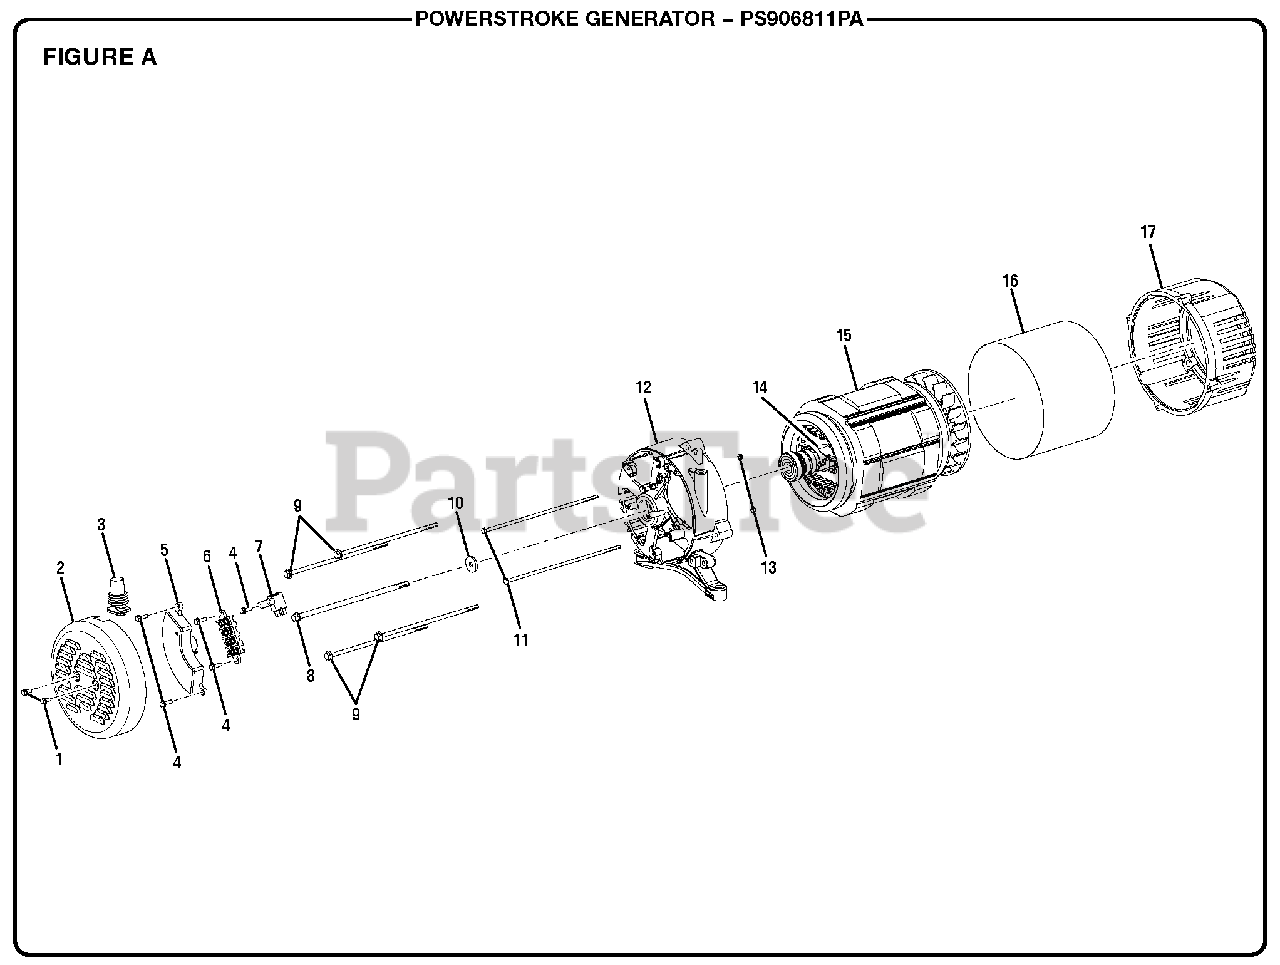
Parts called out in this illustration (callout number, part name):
1	Bolt (M5 x 12 mm, Hex Hd.)
2	Brush Cover
3	Rubber Boot
4	Bolt (M5 x 16 mm, Hex Hd.)
5	Automatic Voltage Regulator
6	Terminal Block
7	Brush Assembly
8	Bolt (5/16-24 x 235 mm, Hex Washer Hd.)
9	Bolt (M6 x 188 mm, Hex Washer Hd.)
10	Washer (ID8 x OD26 x 3t)
11	Bolt (M5 x 210 mm, Hex Washer Hd.)
12	Bearing Housing
13	Hex Nut (M5)
16	Generator Head Cover
17	Adaptor Housing
